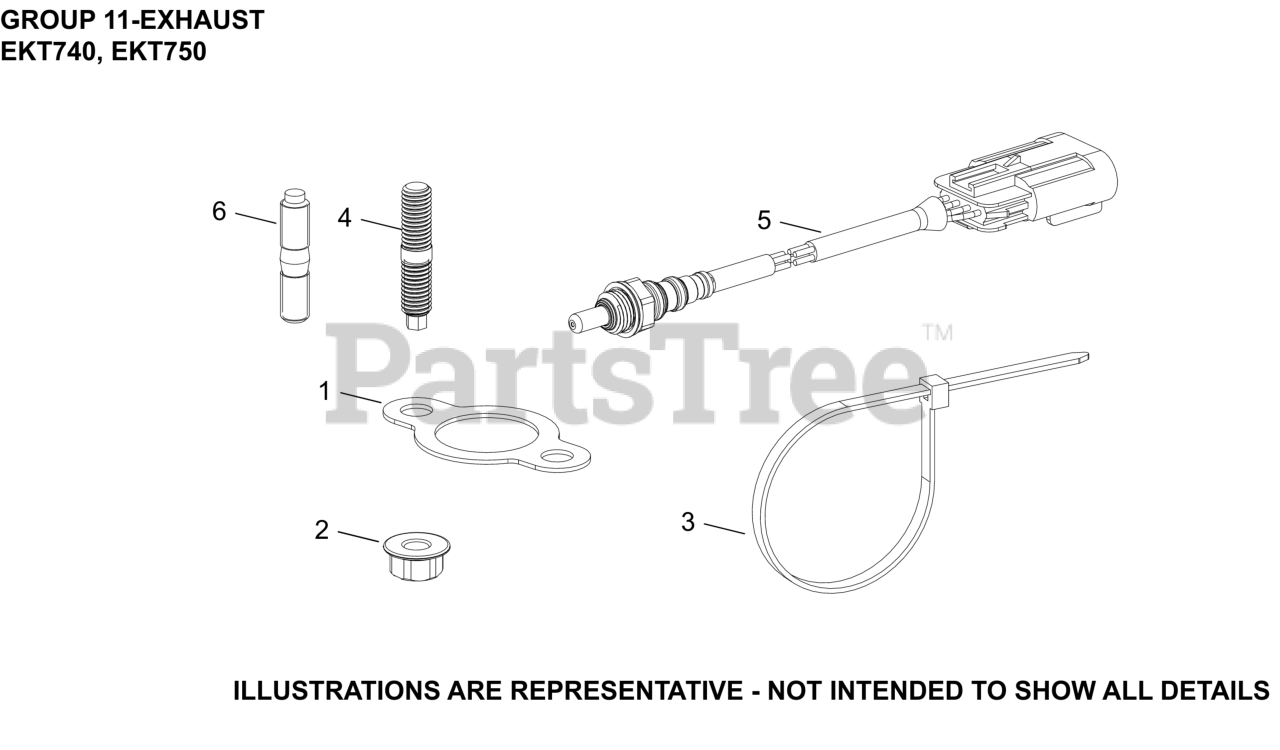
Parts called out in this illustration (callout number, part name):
1	GASKET, EXHAUST MANIFOLD
2	NUT, HEX FLANGE LOCK (M8)
5	SENSOR, OXYGEN (M12 x 1.25 THREADS)
6	STUD, METRIC EXHAUST
